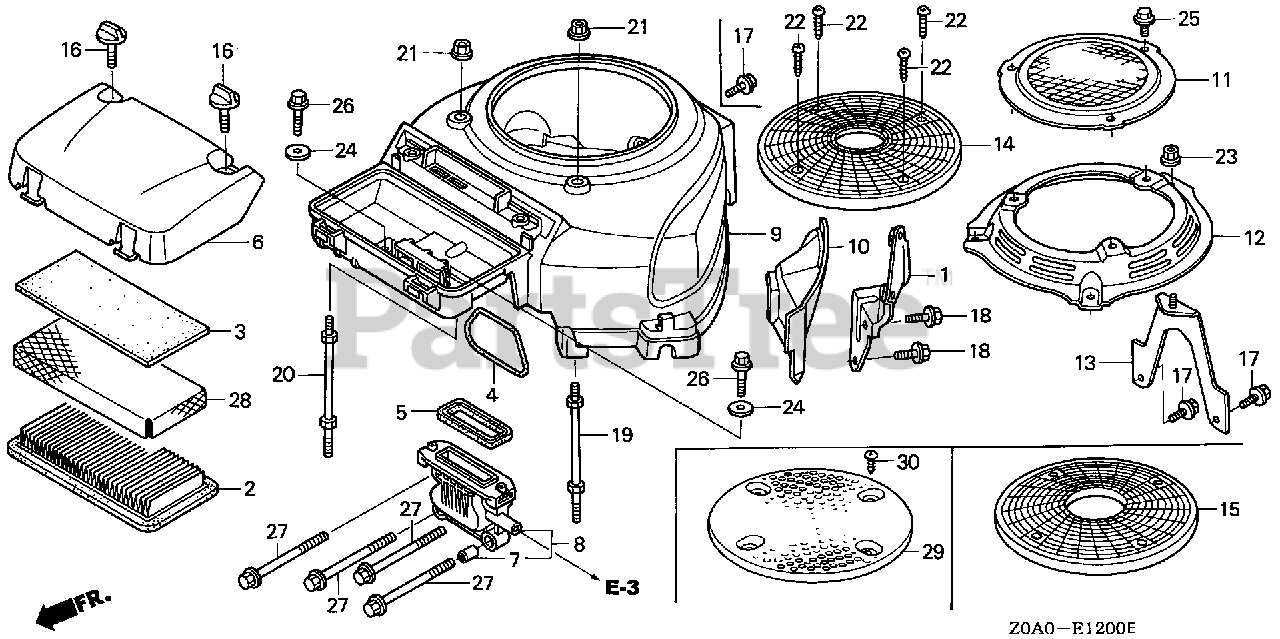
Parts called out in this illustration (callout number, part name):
2	ELEMENT, AIR CLEANER
3	FILTER (OUTER)
4	GASKET, AIR CLEANER
5	SEAL, AIR CLEANER HOUSING
6	COVER, AIR CLEANER
7	COLLAR A, AIR CLEANER
8	ELBOW, AIR CLEANER
9	COVER, FAN *NH1* (BLACK)
10	PLATE, SIDE
11	PROTECTOR, FAN COVER *NH105* (MAT BLACK)
12	SPACER, RECOIL STARTER MOUNTING *NH105* (MAT BLACK)
13	BRACKET, RECOIL MOUNT
14	GRID, SCREEN (D50) *NH1* (BLACK)
16	BOLT, AIR CLEANER (6MM)
17	BOLT, FLANGE (6X14) (CT200)
18	BOLT, FLANGE (6X14)
19	BOLT, L. STUD (IGNITION COIL)
20	BOLT, R. STUD (IGNITION COIL)
22	SCREW, TAPPING (4X30) (PO)
23	NUT, FLANGE (6MM)
24	WASHER, PLAIN (6MM)
25	BOLT, FLANGE (6X8)
26	BOLT, FLANGE (6X12) Use up to Engine SN 1543277.
27	BOLT, FLANGE (6X100)
28	GRID, AIR CLEANER
